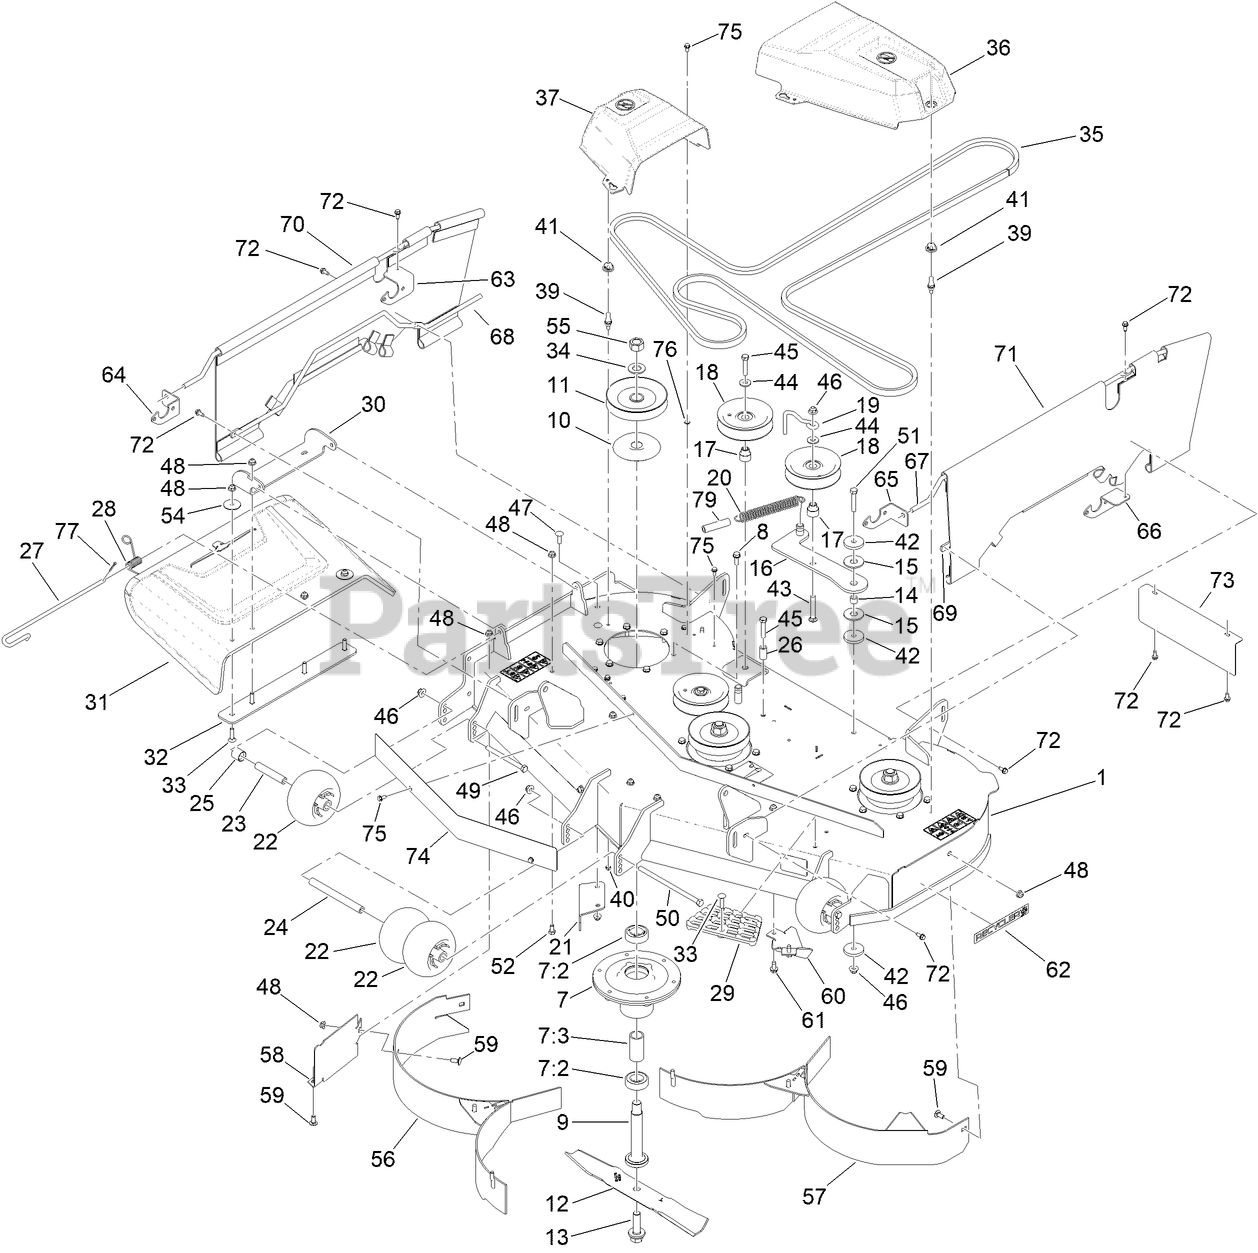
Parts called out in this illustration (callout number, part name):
1	48 IN DECK DECAL ASM
7	SPINDLE ASM
7:2	BEARING-BALL
7:3	SPACER-BEARING
8	SCREW-TAPTITE
9	SHAFT-SPINDLE
10	SHIELD-BEARING
11	PULLEY
12	BLADE-MULCH, 16.50 INCH
13	SCREW-BLADE
14	SPACER
15	WASHER-FRICTION, COMPOSITE
16	IDLER ARM ASM
17	BUSHING-IDLER
18	PULLEY-IDLER, FLAT
19	GUIDE-BELT, IDLER
20	SPRING-EXTENSION
21	BAFFLE-CUTOFF
22	ROLLER-SCALP, ANTI
23	TUBE-SPANNER
24	SPACER-WHEEL
25	SPACER-AXLE, REAR
26	SPACER-FENDER
27	PIN-CHUTE
28	SPRING-TORSION
29	STEP-DECK
30	BRACKET-DEFLECTOR, UPPER
31	DEFLECTOR - MOLDED
32	PLATE-DEFLECTOR
33	BOLT-CARRIAGE
34	WASHER
35	V-BELT
36	COVER-BELT, LH
37	COVER-BELT, RH
39	STUD-BALL
40	NUT-LOCK
41	GROMMET-BALL
42	WASHER-PLAIN
43	SCREW-CARR
44	WASHER-HARDENED
45	SCREW-HH
46	NUT-HF, NI
47	SCREW-CARR
48	NUT-HF
49	SCREW-HH
50	SCREW-HH
51	HHCS 3/8-16 X 2, GR5, CZ
52	SCREW-HH
54	WASHER-FLAT
55	NUT-HEX
56	BAFFLE-RECYCLER
57	BAFFLE-RECYCLER
58	GUARD-BAFFLE
59	BOLT-CARR
60	KICKER-FLANGED
61	SCREW-HWHTF
62	DECAL-RECYCLER
63	BRACKET-FRENCH GUARD
64	BRACKET-FRENCH GUARD
65	BRACKET-FRENCH GUARD
66	BRACKET-FRENCH GUARD
67	ROD-FRENCH GUARD
68	ROD-FRENCH GUARD
69	ROD-FRENCH GUARD
70	GUARD ASM-SIDE, POLY KNIT
71	GUARD ASM-SIDE, POLY KNIT
72	SCREW-HWH
73	PLATE-GUARD REAR
74	PLATE-SHIELD FRONT
75	SCREW-HWH
76	NUT-RETAINING
77	PIN-COTTER
79	HOSE-BREATHER
